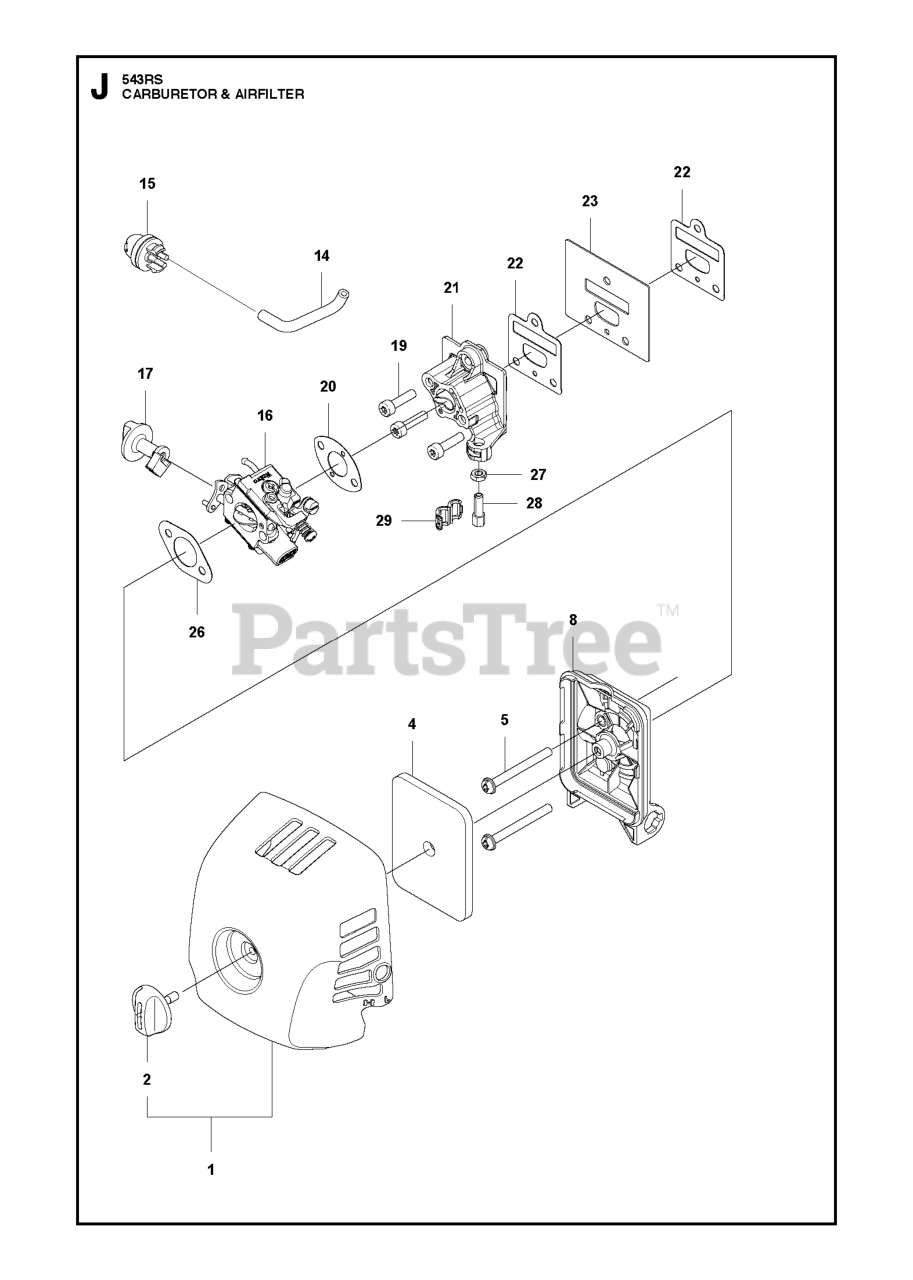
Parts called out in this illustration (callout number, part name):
2	TURNING KNOB GZ40N7
15	AIR PURGE BUBBLE
22	GASKET
